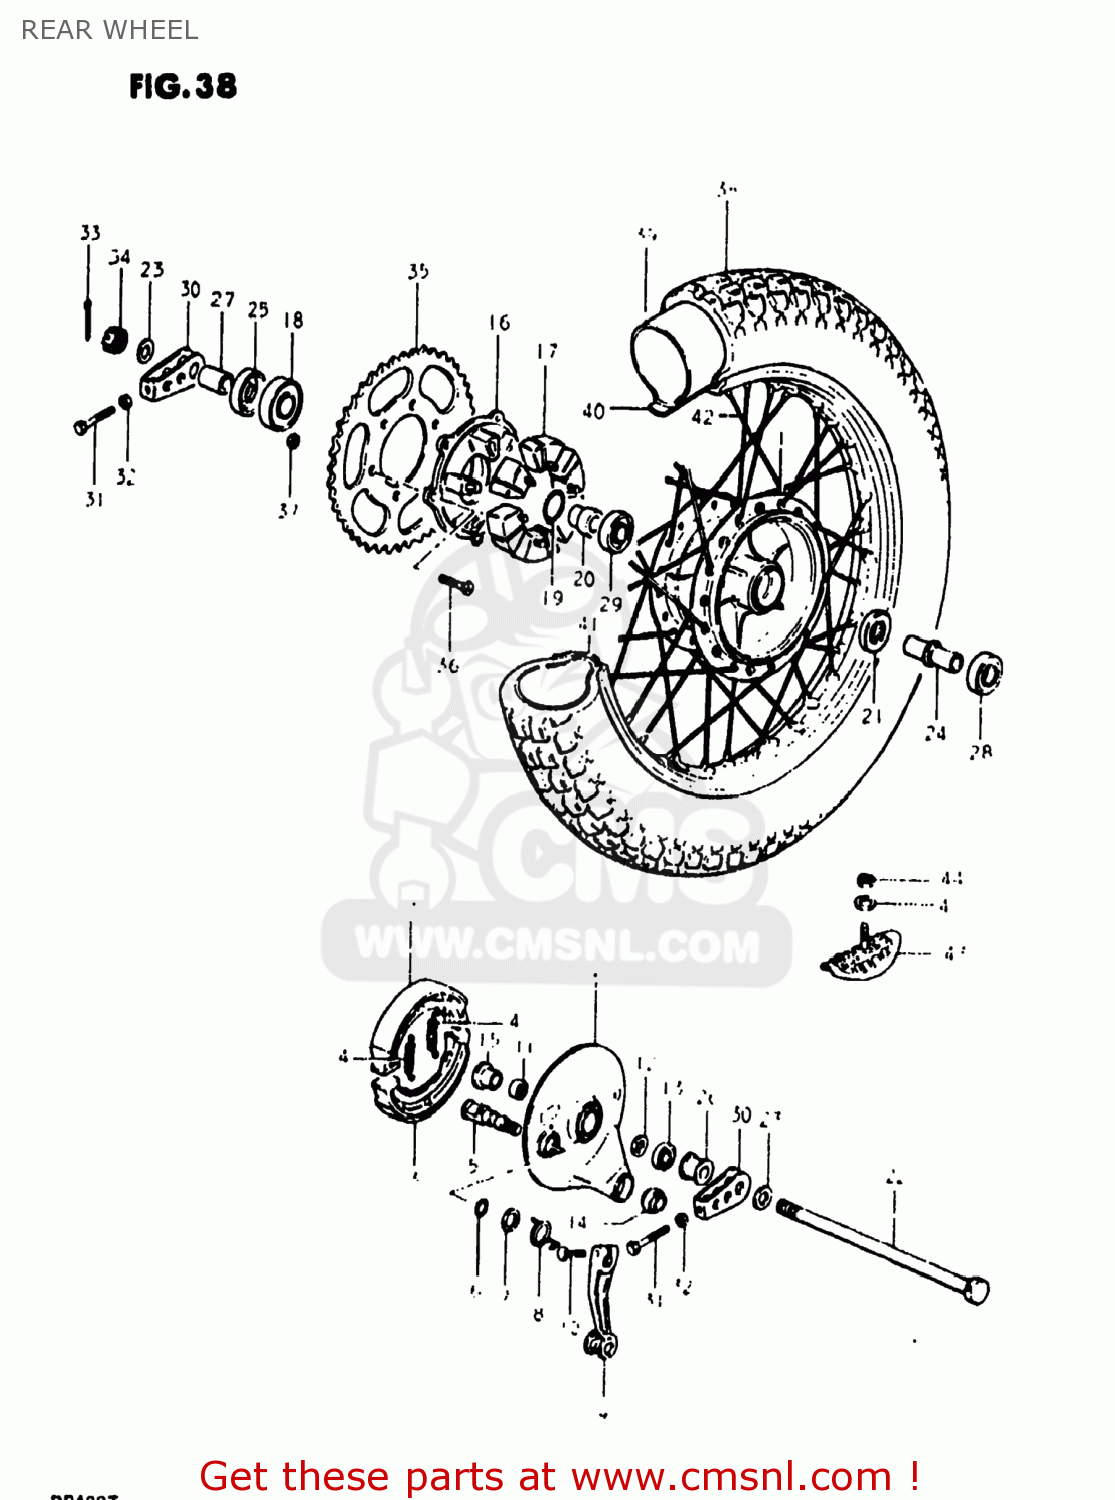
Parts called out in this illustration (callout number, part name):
1	DRUM,REAR HUB
2	PANEL,REAR HUB
3	SHOE,BRAKE (MCA)
4	SPRING
5	CAM,FRONT BRAKE
6	O-RING,BOSS
7	WASHER (15X24X1.6)
8	SPRING
9	LEVER,REAR BRAKE CAM
10	BOLT
11	BEARING(24X31X28)
12	WASHER
13	CVR,RR BRAKE AHR PNL DUST SEAL
14	SPHERICAL BEARING,TORQUE
15	SPACER,REAR HUB PANEL
16	DRUM,REAR SPROCKET MOUNT
17	ABSORBER,RR HUB SHOCK
18	BEARING
19	O-RING
20	SPACER,REAR SPROCKET DRUM
21	OIL SEAL
22	AXLE,REAR
23	WASHER
24	SPACER,REAR HUB BEARING
25	SEAL,OIL(30.5X52X8)
26	SPACER,REAR AXLE,RIGHT
27	SPACER(17X30.5X16.3)
28	BEARING
29	BEARING
30	ADJUSTER,CHAIN
31	BOLT
32	NUT
33	PIN,COTTER
34	NUT
35	SPROCKET,REAR (NT:46)(AL)
36	SCREW(8X33.5)
37	NUT
38	TIRE
39	TUBE ASSEMBLY,WHEEL,INNER
40	PROTECTOR,WHEEL,INNER
41	RIM,REAR WHEEL
42	SPOKE SET,REAR WHEEL
43	STOPPER,BEAD
44	NUT
45	WASHER
